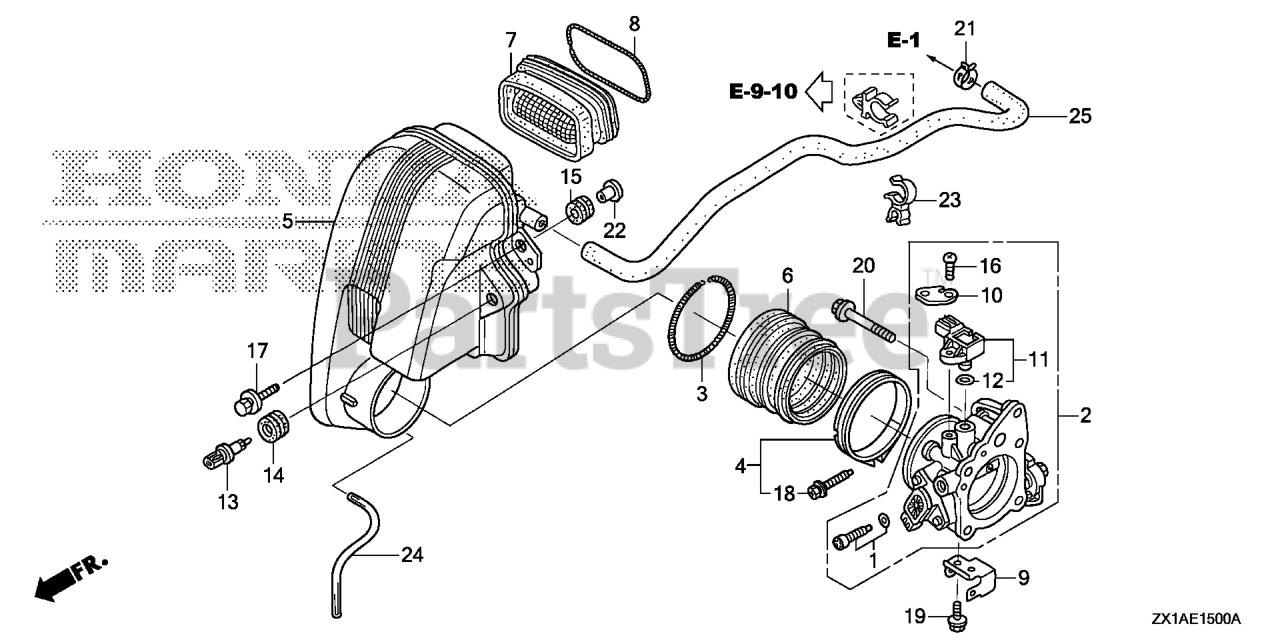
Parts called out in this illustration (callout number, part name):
2	BODY ASSY., THROTTLE
3	SPRING, AIR FLOW TUBE
4	BAND, AIR FLOW
5	CASE, MUFFLER
6	GROMMET, MUFFLER
7	GROMMET, MUFFLER DUCT
8	SPRING, MUFFLER DUCT GROMMET
9	BRACKET E, HARNESS CLIP
10	BRACKET, SENSOR WIRE
11	SENSOR ASSY., MAP
13	SENSOR ASSY., AIR TEMPERATURE (MATSUSHITA DENSHI)
14	GROMMET, TA SENSOR
15	GROMMET, CASE (LOWER)
16	SCREW, PAN (5X18)
17	BOLT-WASHER (6X25)
18	BOLT-WASHER (5X30)
19	BOLT, FLANGE (6X12)
20	BOLT, FLANGE (8X60)
21	CLAMP, TUBE (D17)
22	COLR, CDI UNIT CASE
22	COLLAR, MODULE IGNITION CONTROL CASE (CDI)
23	CLAMP, FUEL HOSE
24	BULK HOSE, VINYL (4X7X8000) (95003-07(95003-07001-60M) (CARBURETOR NO.)
25	BULK HOSE, VACUUM (12X1000) (12X740)
